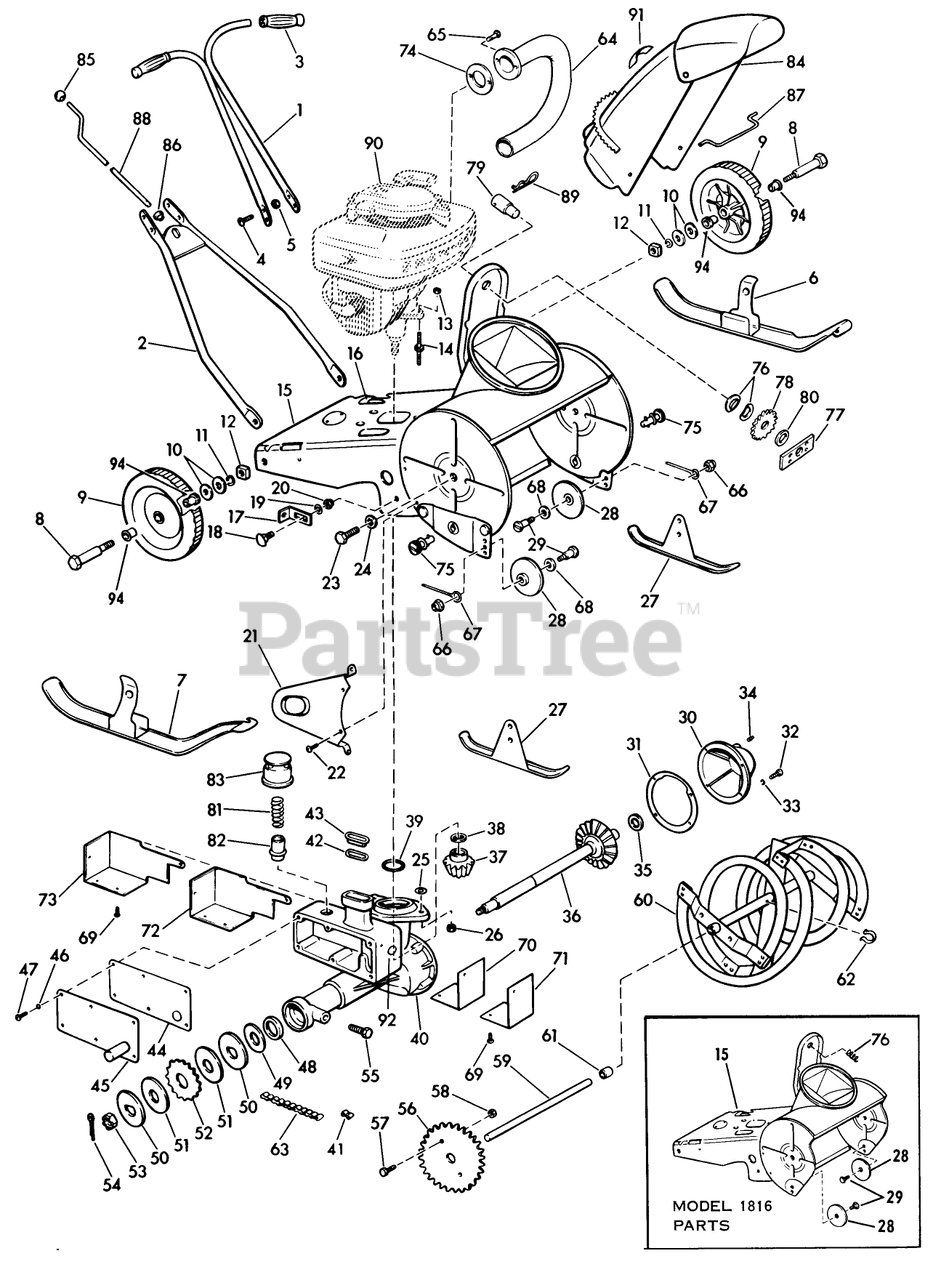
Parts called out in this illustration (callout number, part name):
5	STOP NUT
9	Wheel Assembly-Rear
11	WASHER, LOCK
15	Base, Housing Brkt. Assy.
15	Base, Housing and Bracket Assy.
20	Nut-Huglok
25	Washer-G-case to Base Stud
29	Stud-Front Wheel
30	Cover-Gearcase
32	Screw-Gearcase Cover
35	Thrust Washer-Driveshaft Gear
36	Driveshaft and Gear Assembly
38	Thrust Washer-Pinion Gear
39	O Ring-G-case to Crankcase
50	Washer-Steel "D" Hole
54	Cotter Pin-Wheel
55	Screw-Stabilizer Bracket
58	Nut-Huglok
68	Washer
76	Washer-Sprocket Bow
76	Spring
90	Snow Boy Engine-C-12AA
91	Decal-Oil Instruction
92	Plug-Core
